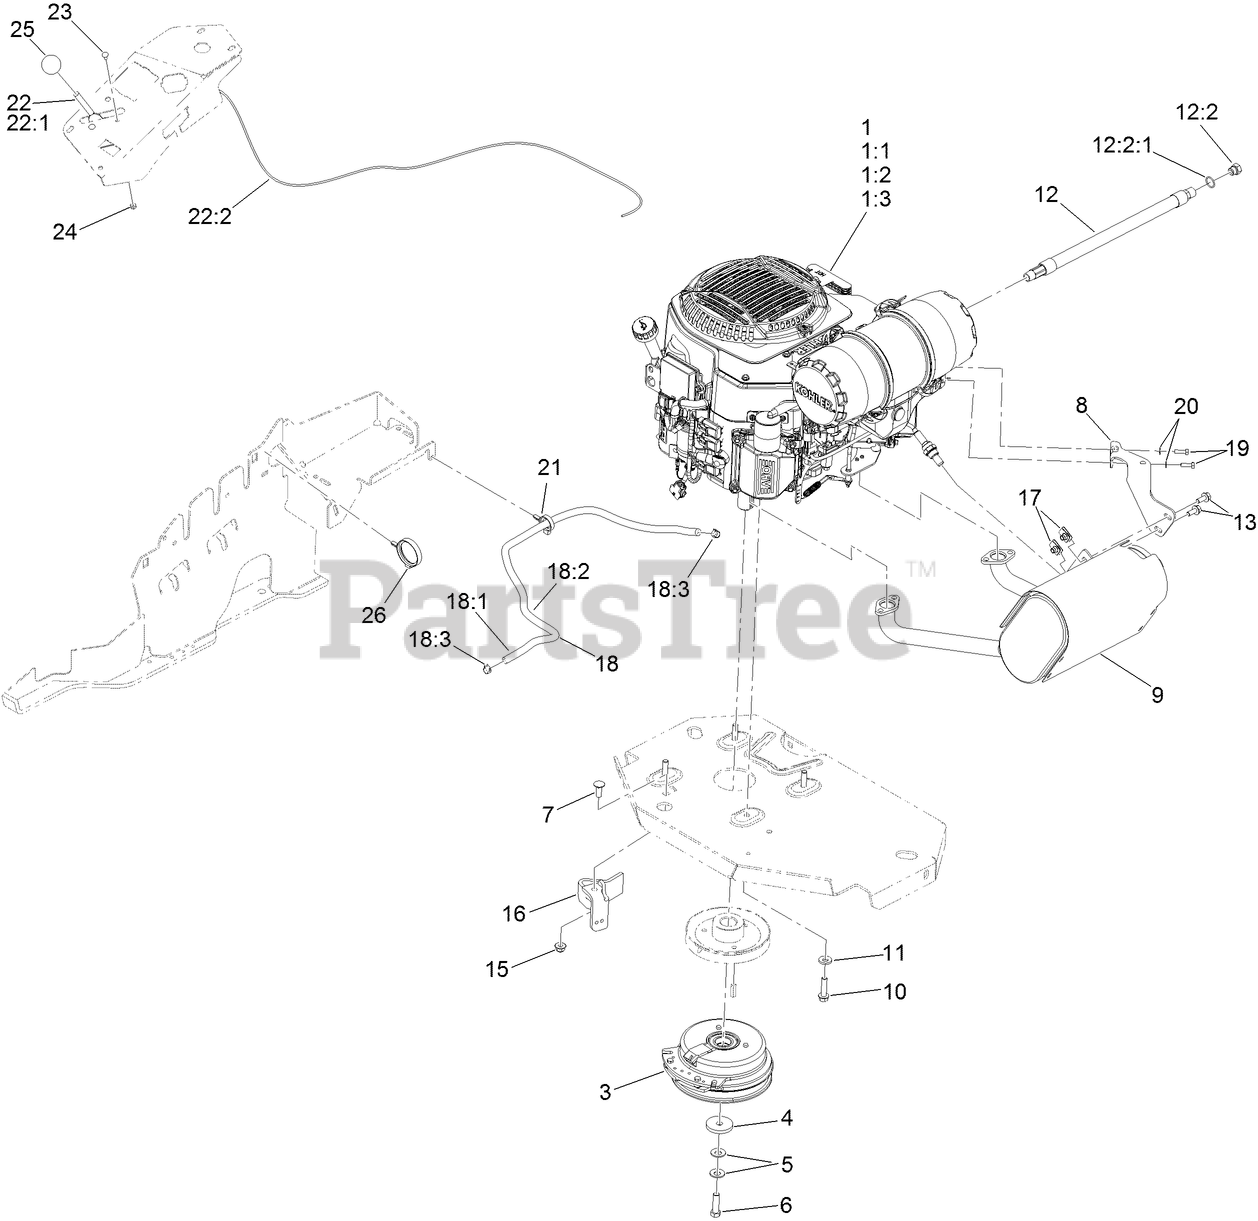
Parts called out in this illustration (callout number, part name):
1:1	KOHLER 52 050 02-S ENGINE OIL FILTER
1:2	KOHLER 25 083 01-S ENGINE AIR FILTER
1:3	KOHLER 25 083 04-S SAFETY FILTER
3	CLUTCH KIT
4	WASHER-CLUTCH
5	WASHER-SPRING
6	SCREW-HH, W/LOCTITE
7	SCREW-CARR
8	MUFFLER BRACKET KIT
9	MUFFLER KIT
10	SCREW-HWH
11	WASHER-BELLEVILLE
12	OIL DRAIN HOSE ASM
12:2	PLUG-HH
12:2:1	O-RING
13	SCREW-HHF
15	NUT-HF, NI
16	CLUTCH-ANCHOR
17	NUT-U
18	FUEL LINE ASM
18:1	HOSE-FUEL
18:2	SLEEVE-THERMAL
18:3	CLAMP-HOSE
19	SCREW-HH
20	WASHER-SPRING
21	CLAMP-HOSE
22	THROTTLE CONTROL ASM
22:1	LEVER-THROTTLE
23	BOLT-CARR
24	NUT-LOCK, NI
25	KNOB-BALL
26	CLAMP-HARNESS
